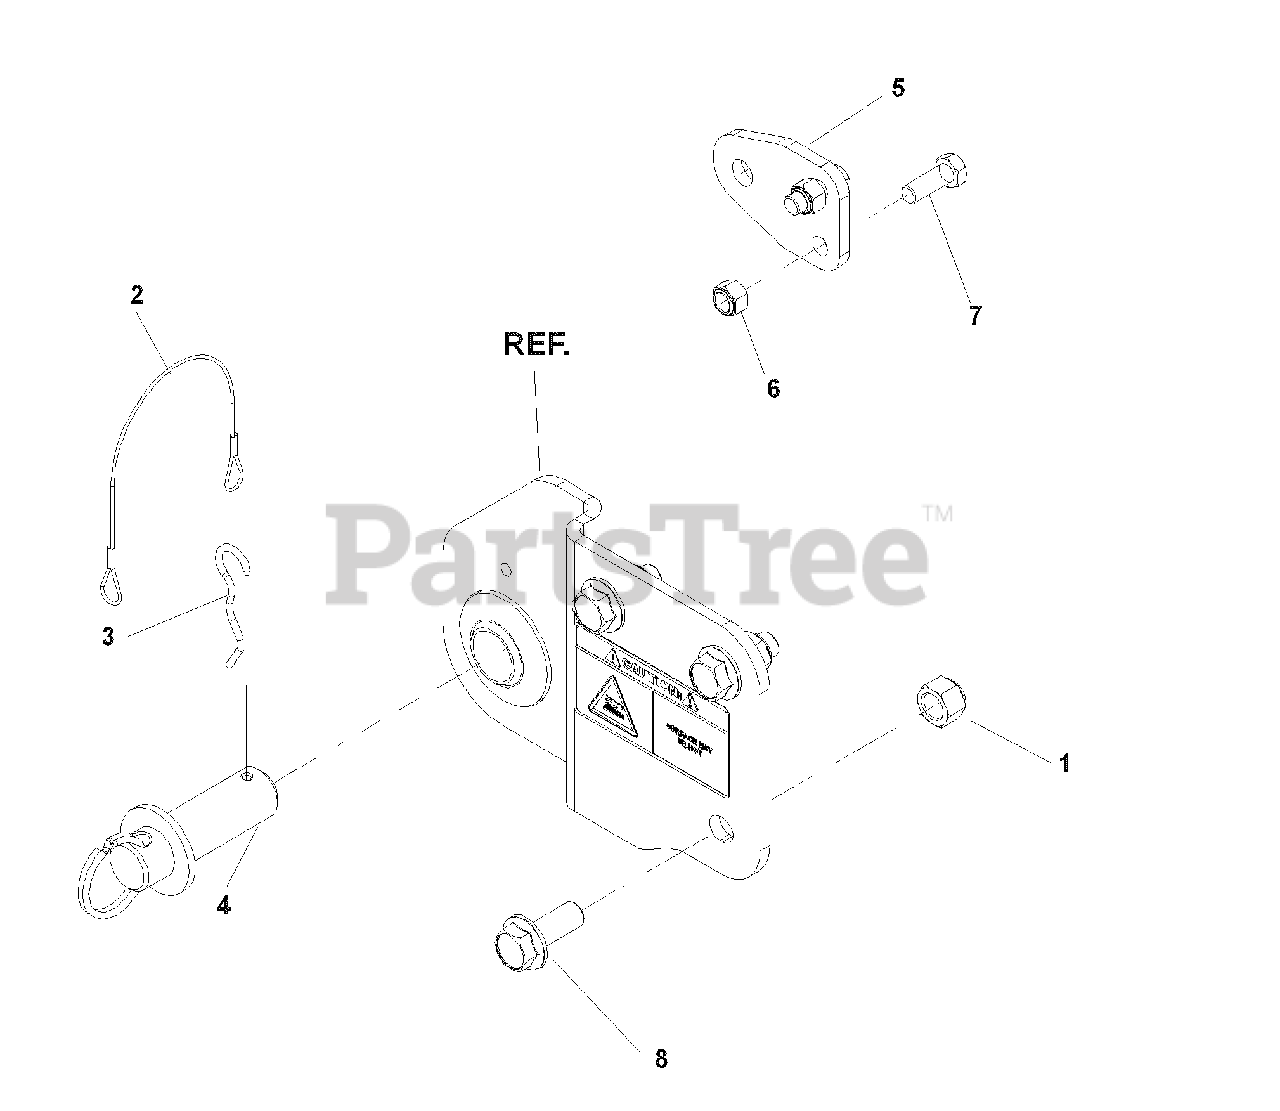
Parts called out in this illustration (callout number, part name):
1	NUT, 1/4-13, NYLOC
5	SUPPORT BRACKET
6	NUT, 3/8-16, NYLOC
7	HCS, 3/8-16x1
8	BOLT, 1/2-13x1 1/4, WHIZLK
